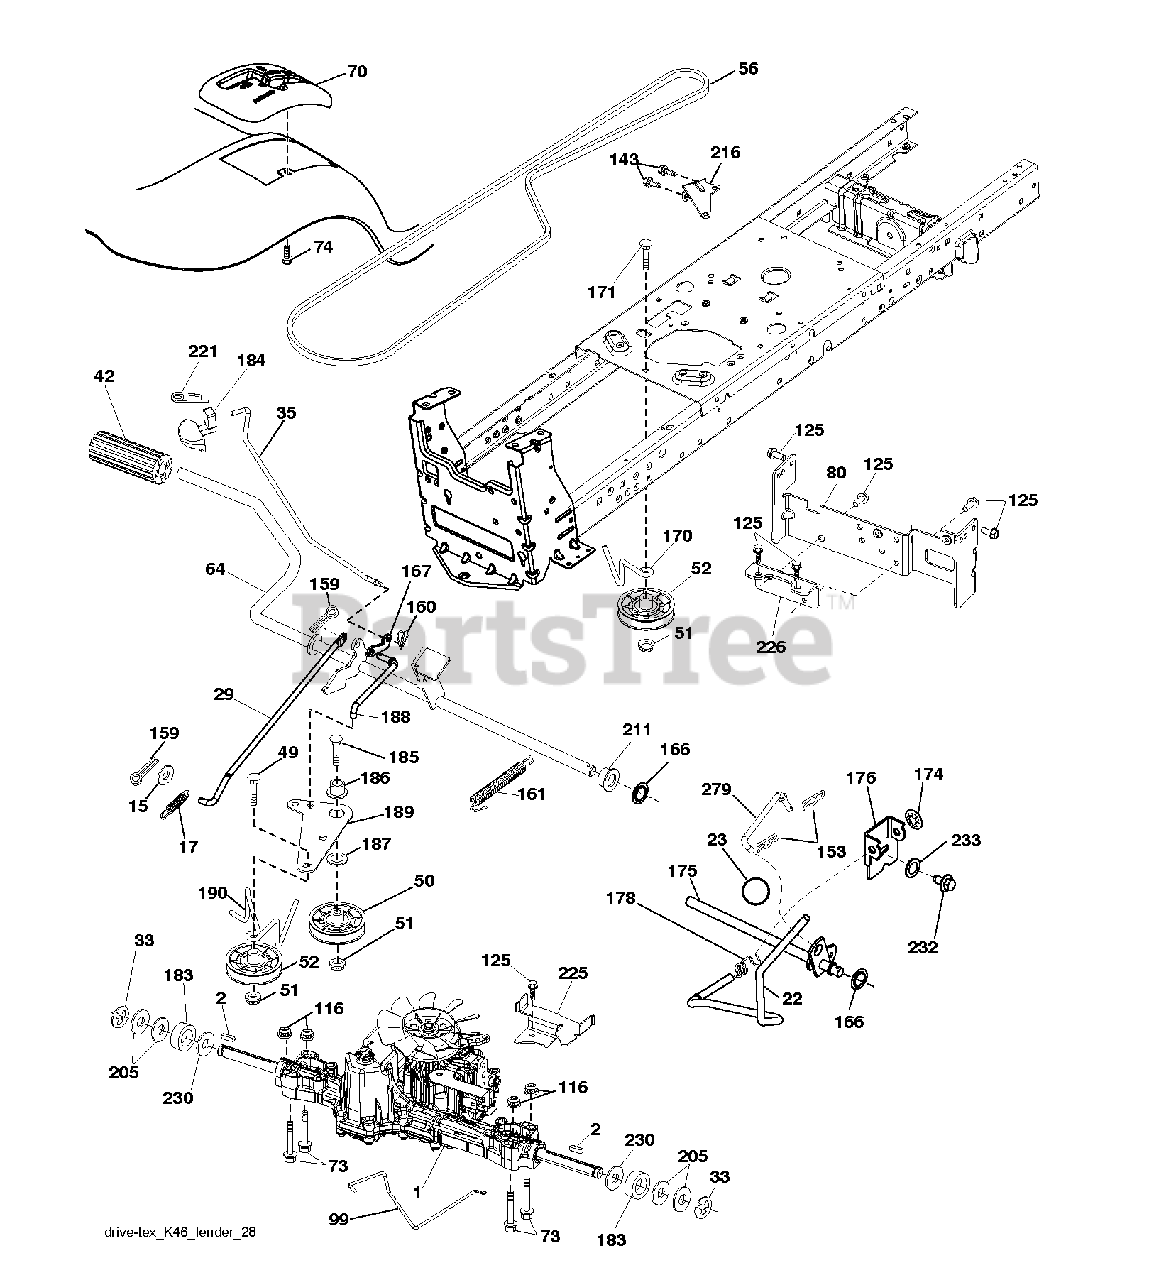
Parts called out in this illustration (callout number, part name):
2	SQUARE KEY
17	SPRING.BRAKE.K46.GREEN
22	ROD.SHIFT.FENDER.TLT.2006
23	PISTOL KNOB
29	ROD.BRAKE.K46
33	E-RING LT
35	ROD.BRAKE.PARKING.LT.T
42	PEDAL COVER T
49	BOLT
50	IDLER.FLAT.910.OFFSET
51	NUT LOCK FLG 3/8-16 UNC
52	IDLER.V-GROOVE.910.OFFSET
64	SHAFT.ASM.PEDAL.BRAKE.
70	CONSOLE.SHIFT.STL.HYD.BLACK
73	BOLT HEX 5/16-18 GR 5
74	SCREW.HI-LO.CONSOLE
80	STRAP.TORQUE.K46.K57R.TT
99	ROD.SPRING.BYPASS.K46.LT.Z
116	NUT LOCK HEX FLANGE 5/16-18
125	SCREW
153	RETAINER M
159	COTTER PIN
160	RETAINER CLIP
161	SPRING, RETURN LT
166	NUT.PUSH.625
167	LATCH.BRAKE.SPRING
170	KEEPER.V-IDLER.CENTER.
171	BOLT
174	NUT.PUSH.500.2006
175	SHAFT ASM SHIFT
176	ARM.CLEVIS.ROD.SHIFT
178	SPRING.SHIFT.GT2006
183	SPACER AXLE
184	HANDLE.PARKING.BRAKE.LTTEX.667
186	SPACER.RETAINER
187	WASHER 12/32X2X10GA
188	LINK.CLUTCH.GROUND.DRIVE
189	BELLCRANK.GROUND.DRIVE.TEX.
190	KEEPER.BELLCRANK.DRIVE
211	BUSHING.SHAFT.BRAKE.HAND
216	BRACKET.PULLEY.IDLER.W/TEX
221	RETAINER.SPRING.CLIP.H
225	KEEPER.BELT.TRANSAXLE.K46
226	BRACKET.MOUNT.TORQUE.K46.TLT
230	WASHER.HARDENED
232	BOLT FIN HEX 7/16-14 X 1
233	WASHER SERRATED
279	LINK SHIFT
